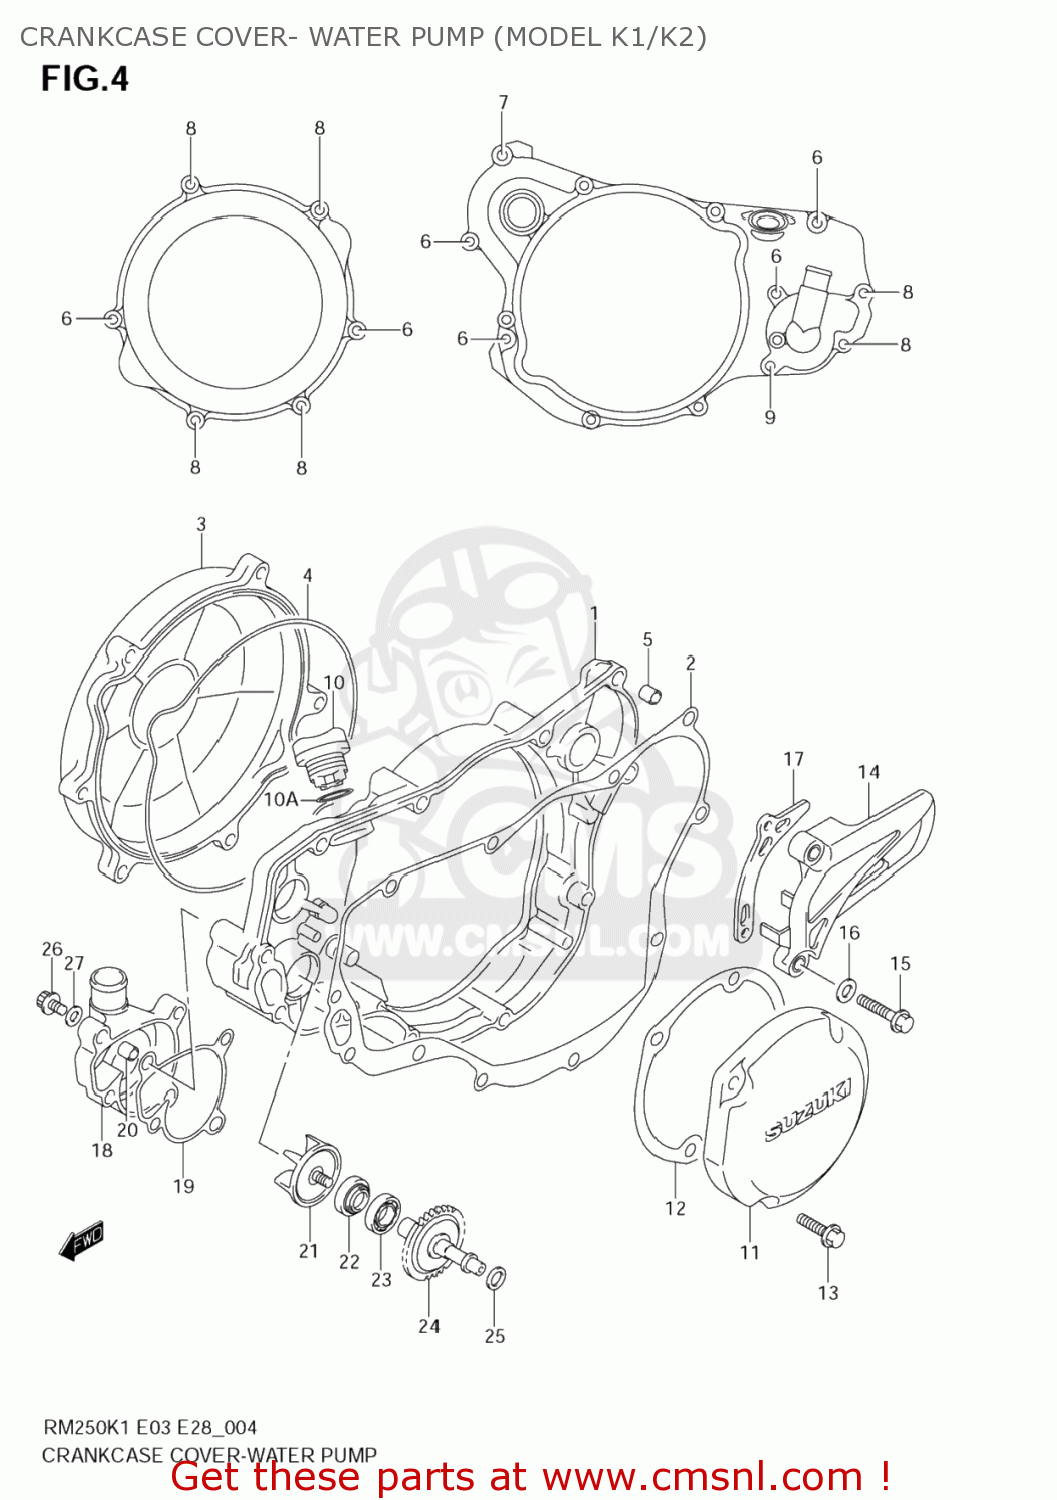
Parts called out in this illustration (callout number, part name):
1	COVER,CLUTCH
2	GASKET,COVER (NAS)
3	COVER,CLUTCH O
4	O RING,CL COVER OUTER
5	PIN
6	SCREW
7	BOLT(6X30)
8	BOLT
9	BOLT
10	PLUG,OIL FILLER
10A	O RING(D:3.1,ID:16.8)
11	COVER,MAGNETO
12	GASKET,MAGNETO COVER
13	SCREW
14	COVER,ENGINE SPROCKET
15	BOLT(6X30)
16	WASHER
17	PLATE,FR CHAIN GUIDE
18	CASE,WATER PUM
19	GASKET,WATER PUMP CASE (NAS)
20	PIN
21	IMPELLER,WATER
22	SEAL,WATER PUMP OIL
23	BEARING
24	SHAFT,WATER PUMP
25	SHIM(8.8X14X1)
26	BOLT
27	GASKET(6.2X11X1).2 (NAS)
